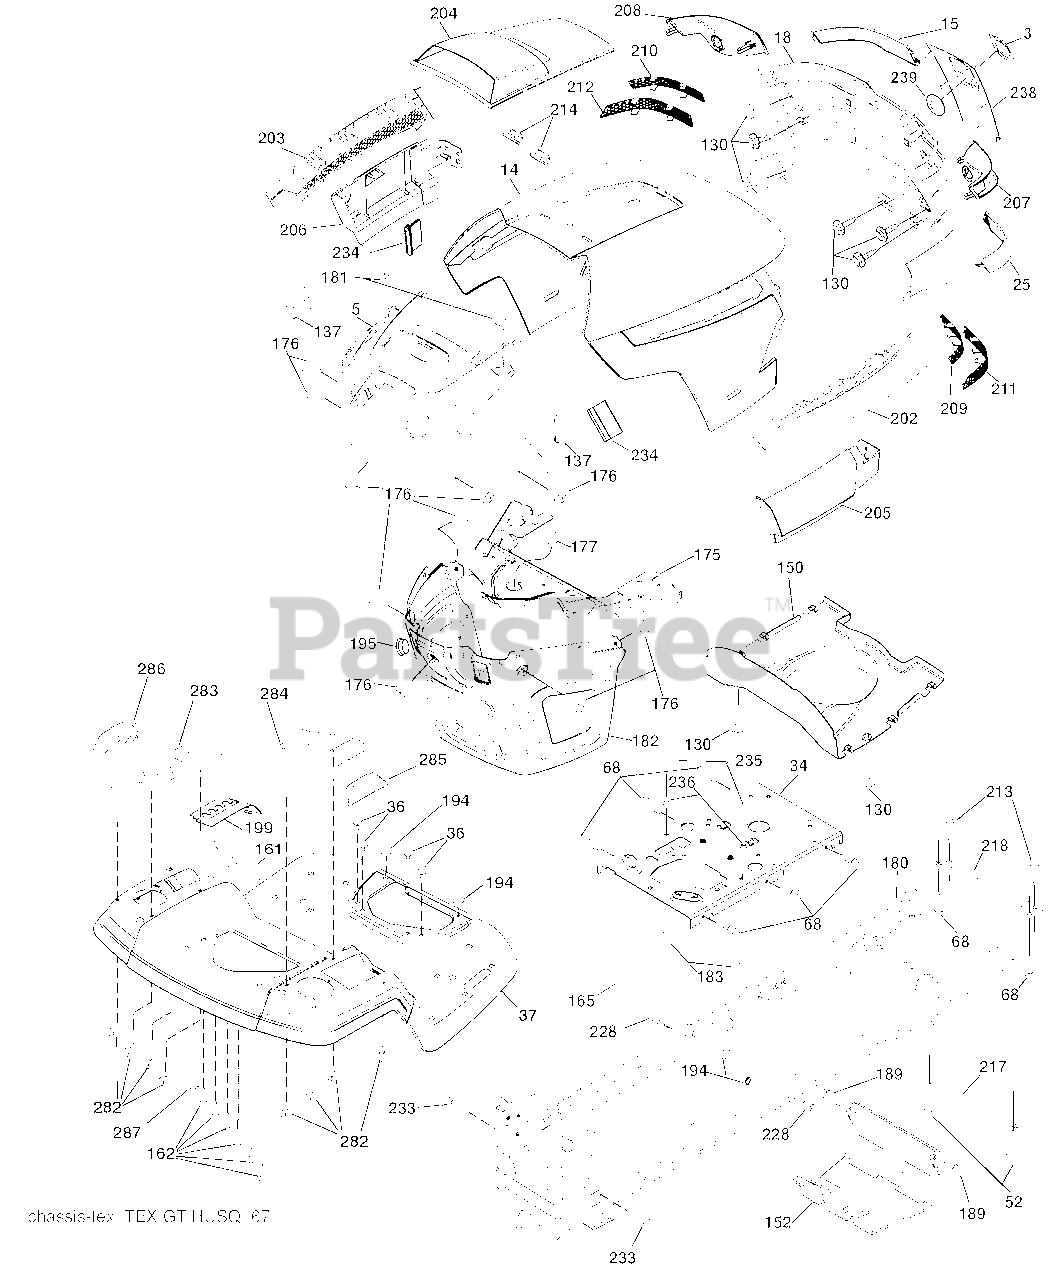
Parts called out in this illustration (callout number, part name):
3	Logo
14	Hood
18	Grille Asm.
34	Plate Engine
36	Screw 5/16-18 x 3/4
52	Nut Lock 5/16-18
68	Screw 5/16-18 x 1/2
130	Screw #10 x 0.750 BOS Thread
137	Bumper Dash
152	Shield Browning
161	Window Fuel
165	Support Tank Rear
175	Crossmember
176	Screw 10-24 x 5/8
177	Bushing Steering
180	Chassis
181	Bushing Mtg. Fender Crgo
182	Dash Lower
183	Bolt Fin Hex 5/16-18 unc x 1-1/4
189	Screw 5/16-18 x 3/4
194	Nut Lock Hex Flange 5/16-18
195	Plug Hole Dash Lower
199	Plate Deck Lift
202	Vent Side Hood RH
203	Vent Side Hood LH
204	Vent Top Hood
205	Skirt Hood Side RH
206	Skirt Hood Side LH
209	Insert Hex Top RH
210	Insert Hex Top LH
211	Insert Hex Bottom RH
212	Insert Hex Bottom LH
213	Bolt 5/16-18 unc x 3/4
214	Clip Retainer Tinner
218	X-Piece Hood Stop
228	Stud Fastner
233	Bolt, Shoulder
234	Bumper Hood
235	Spacer Fender
236	Nut Lock 5/16-18 unc
282	Clip Retainer Console
283	Console Asm. Decklift
284	Console Asm.
285	Console Insert RH
286	Console Insert LH
287	Screw Hex Washead 1/4-20 x 3/8
